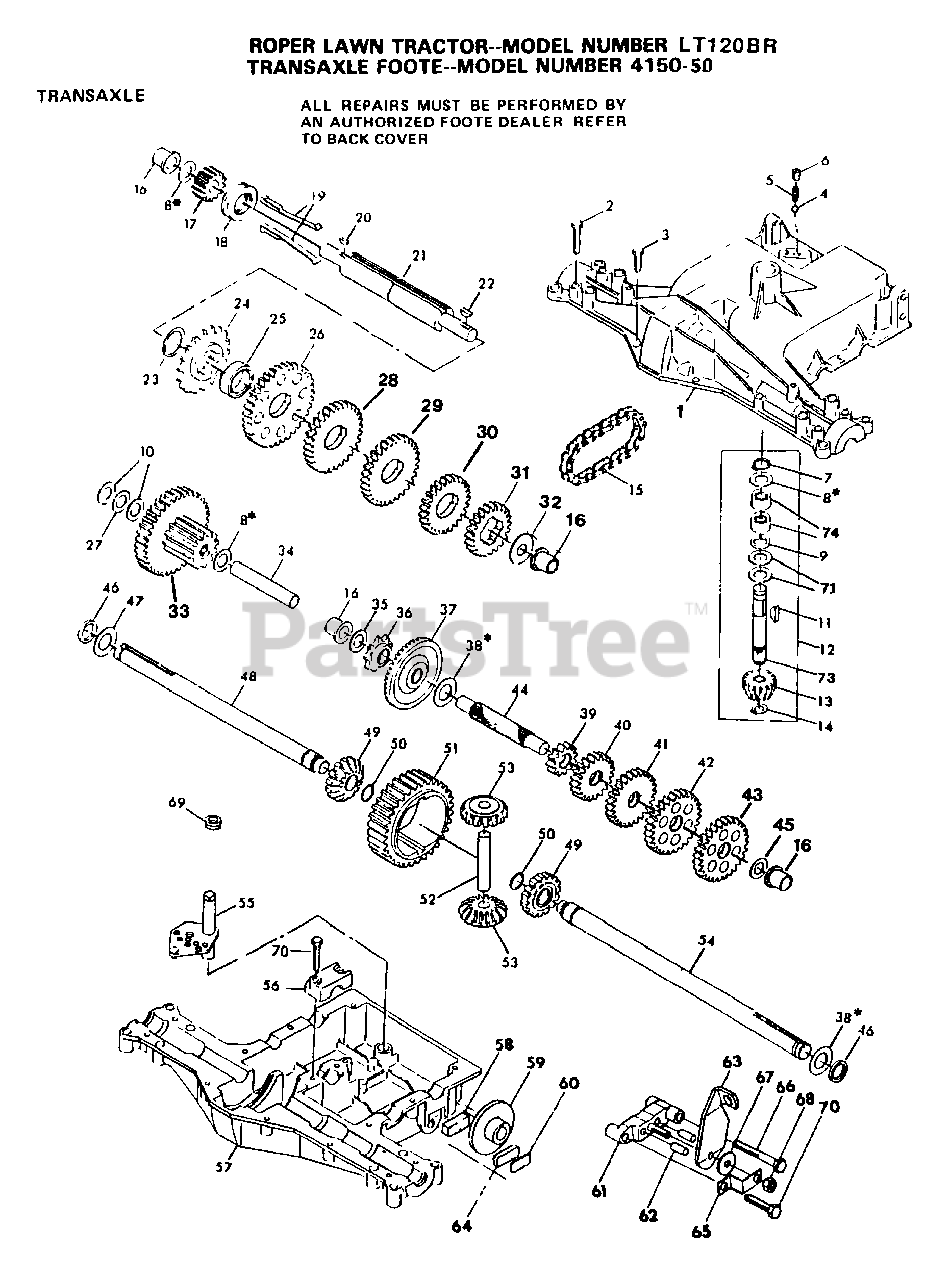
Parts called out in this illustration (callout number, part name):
1	HOUSING, UPPER
2	SCREW 1/4-20 X 1.31
3	SCREW 1/4-20 X .875
4	BALL DETENT
5	SPRING, DETENT
6	SCREW, SET
7	RING RETAINING
8	WASHER PLAIN
8	WASHER, PLAIN .632 X 1.00 X .026
8	WASHER, PLAIN .632 X 1.00 X .060
10	WASHER PLAIN
11	KEY WOODRUFF #9
12	ASSY KIT INPUT SHAFT
13	PINION, BEVEL, 14 TEETH
14	RING, RETAINING
15	CHAIN, 24 PITCHES
16	BEARING, FLANGE
17	GEAR SPUR, 14 TEETH
18	COLLAR CLUTCH
19	KEY, CLUTCH
20	KEY WOODRUFF #3
21	SHAFT, INTERMEDIATE
22	KEY, WOODRUFF, #61
23	RING, RETAINING
24	SPROCKET, 18T
26	GEAR, SPUR, 37 TEETH
27	SPACER .630 X 1.00 X .169
28	GEAR, SPUR, 30 TEETH
29	GEAR, SPUR, 25 TEETH
32	WASHER, PLAIN .640 X 1.37 X .061
33	ASSY GEAR COMB 12&35 TEETH
34	SHAFT, IDLER
35	WASHER PLAIN
36	SPROCKET, 9 TEETH
37	GEAR, BEVEL, 42 TEETH
38	WASHER PLAIN
38	WASHER, PLAIN .758 X 1.25 X .031
39	GEAR, SPUR, 12 TEETH
40	GEAR, SPUR, 20 TEETH
41	GEAR, SPUR, 25 TEETH
42	GEAR, SPUR, 31 TEETH
44	SHAFT, DRIVE
45	WASHER, PLAIN .632 X 1.00 X .060
47	WASHER, PLAIN .758 X 1.25 X .031
49	GEAR, MITER, 15 TEETH
50	RING, RETAINING
51	GEAR, SPUR, 32 TEETH
52	SHAFT, CROSS
53	GEAR, MITER, 15 TEETH
55	ASSY SHIFTER
56	CAP, SUPPORT
57	PUCK, FRICTION
58	PUCK, FRICTION
59	DISC, BRAKE
61	No Desciption for Part
62	PIN, DOWEL
63	LEVER, ACTUATING
64	PUCK, FRICTION
65	BRACKET, ANTI-ROTATION
67	WASHER, PLAIN .321 X 1.00 X .055
68	LOCKNUT 5/16-24
70	SCREW TAPPING
71	WASHER, PLAIN .632 X 1.38 X .046
